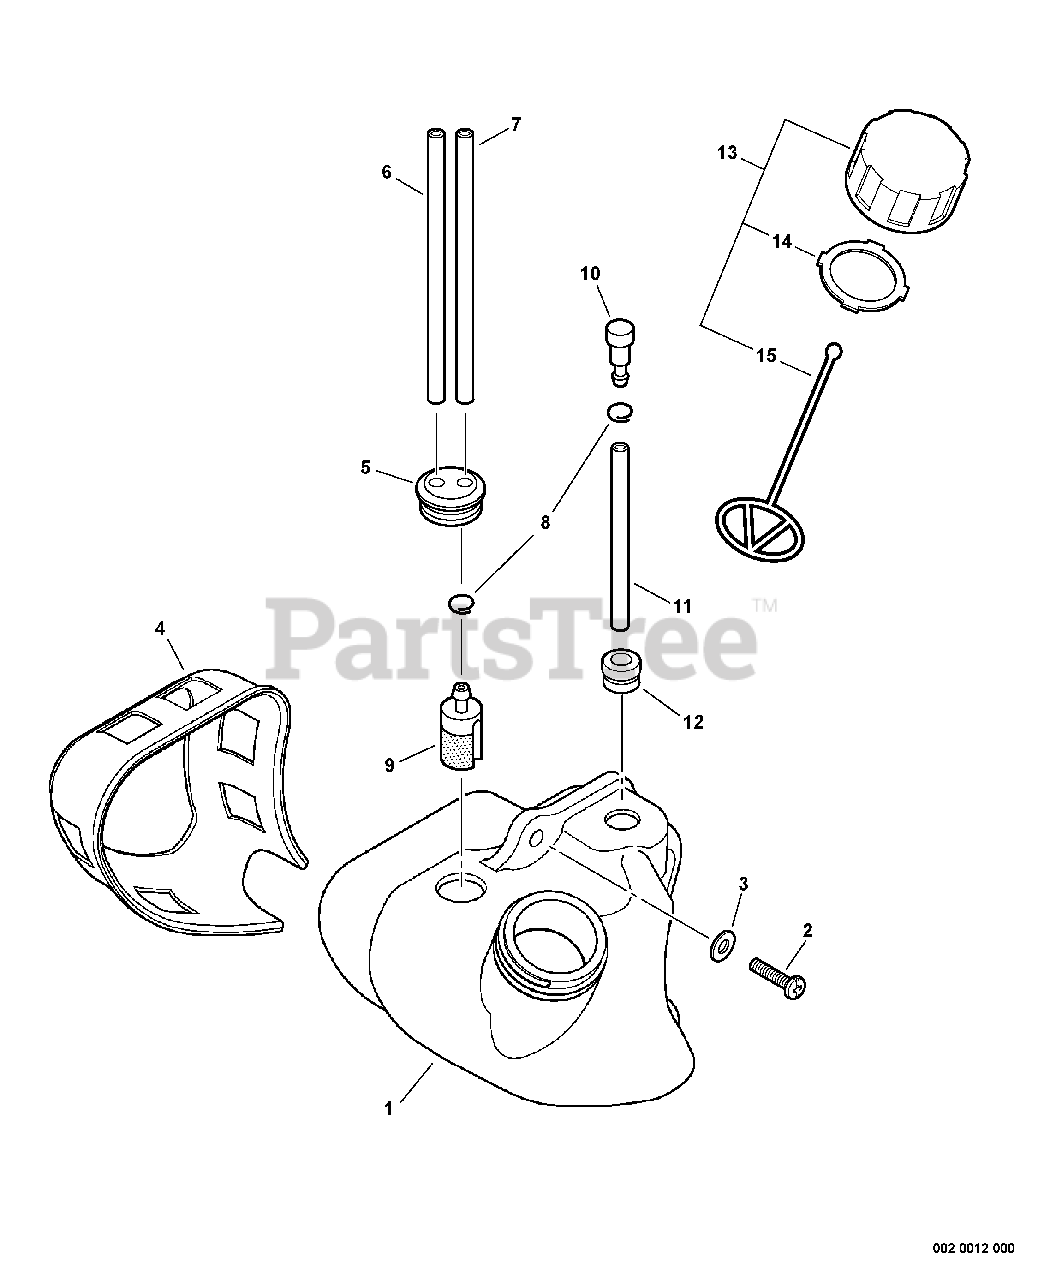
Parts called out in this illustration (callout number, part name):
1	TANK, FUEL
2	SCREW, TAPPING 5×20
3	WASHER 5.5×12×0.8
4	GUARD, FUEL TANK
5	GROMMET, FUEL
6	PIPE, FUEL 3×6×85 CLEAR
7	PIPE, FUEL 3×5×175 BLACK
8	CLIP 6 MM
9	FILTER, FUEL
10	VENT ASSY
11	PIPE, FUEL VENT 3×5×50
12	GROMMET
13	CAP ASSY, FUEL
14	GASKET, FUEL CAP
15	CONNECTOR, CAP L= 100 MM
